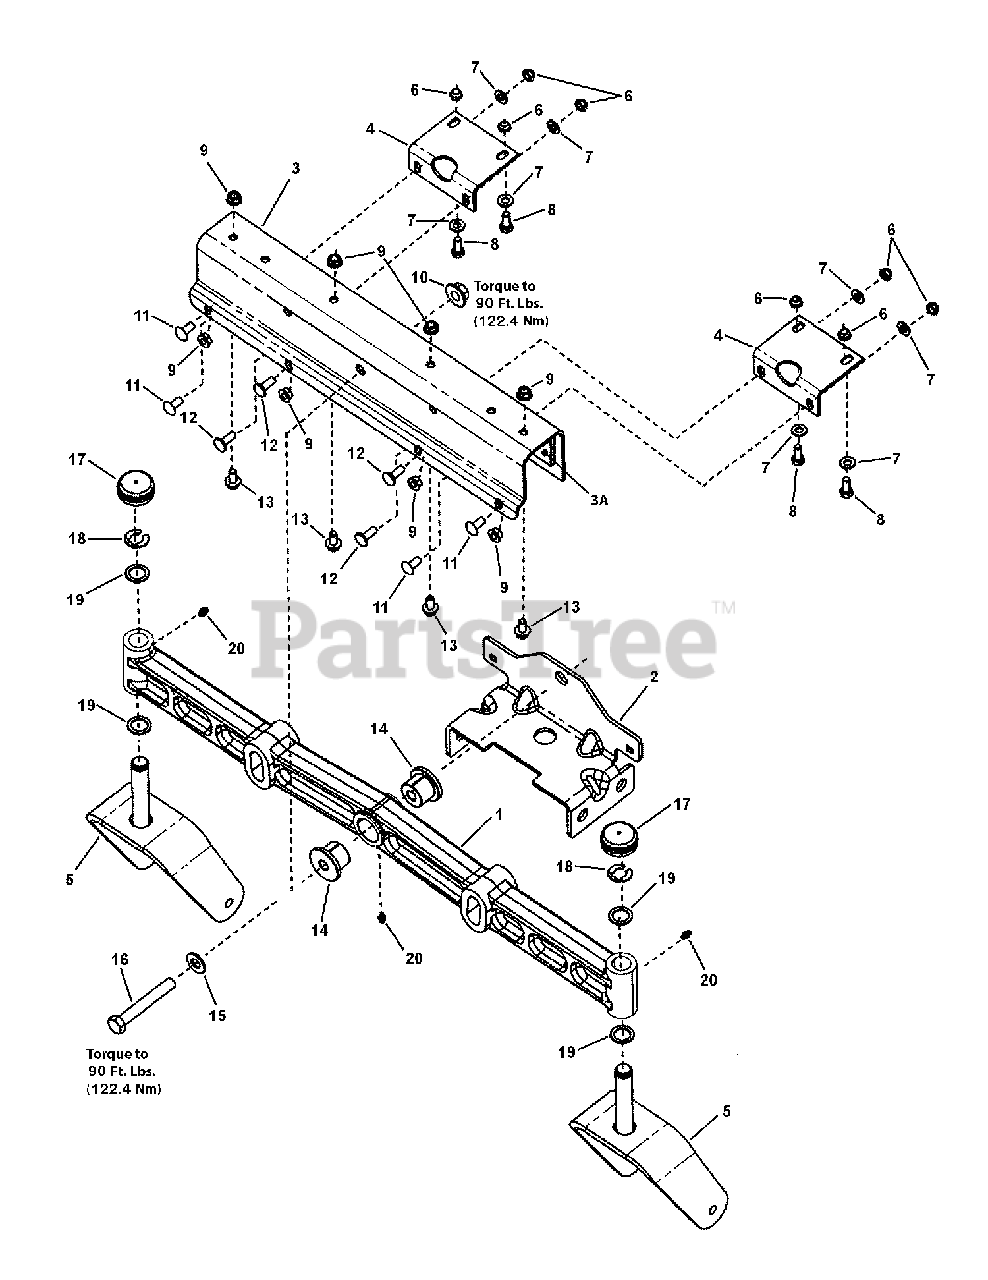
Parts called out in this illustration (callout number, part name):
1	AXLE, Front
2	BRACKET, Hanger, Front, 46 / 52
3	BRACKET, Axle
3A	PLATE, Friction, Adhesive Backed
4	BRACKET, Axle Support
5	CASTER YOKE & SPINDLE
6	NUT, Hex Top Lock, 5/16-18, GR B
7	WASHER, Flat, 5/16
8	CAPSCREW, Hex Flange, 5/16-18 x 3/4, GR 5
9	NUT, Flange Lock, 5/16-18
10	NUT, Hex Flange, Two Way Lock, 1/2-13
11	BOLT, Carriage, Short Neck, 5/16-18 x 3/4, GR 5
12	BOLT, Carriage, Short Neck, 5/16-18 x 7/8, GR 5
13	BOLT, Hex Flange Lock, 5/16-18 x 5/8, GR 5
14	BUSHING, Axle Pivot
15	WASHER, Flat, 1/2
16	CAPSCREW, Hex Head, 1/2-13 x 3-1/2
18	RING, Klipring, 3/4
19	WASHER, 0.750 ID x 1.60 OD x .05 Thick
20	LUBE FITTING, 3/16" Press Fit
